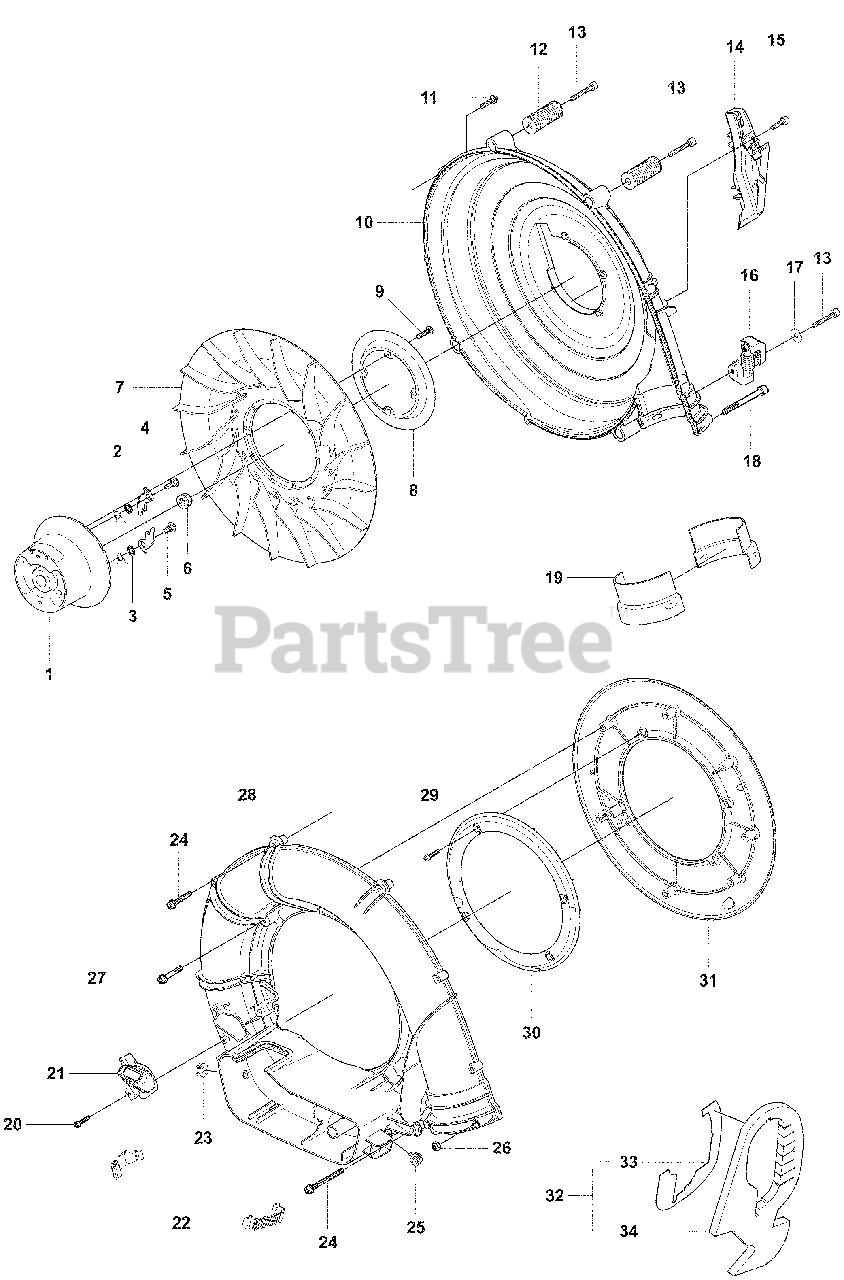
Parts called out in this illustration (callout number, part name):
5	Screw, M5 X 14
6	Nut with Washer
17	Washer, M5 Large
22	Top Cover Buckle Clip, Orange
27	Screw, M5 X 16
33	TAPE DOUBLE-STICK
